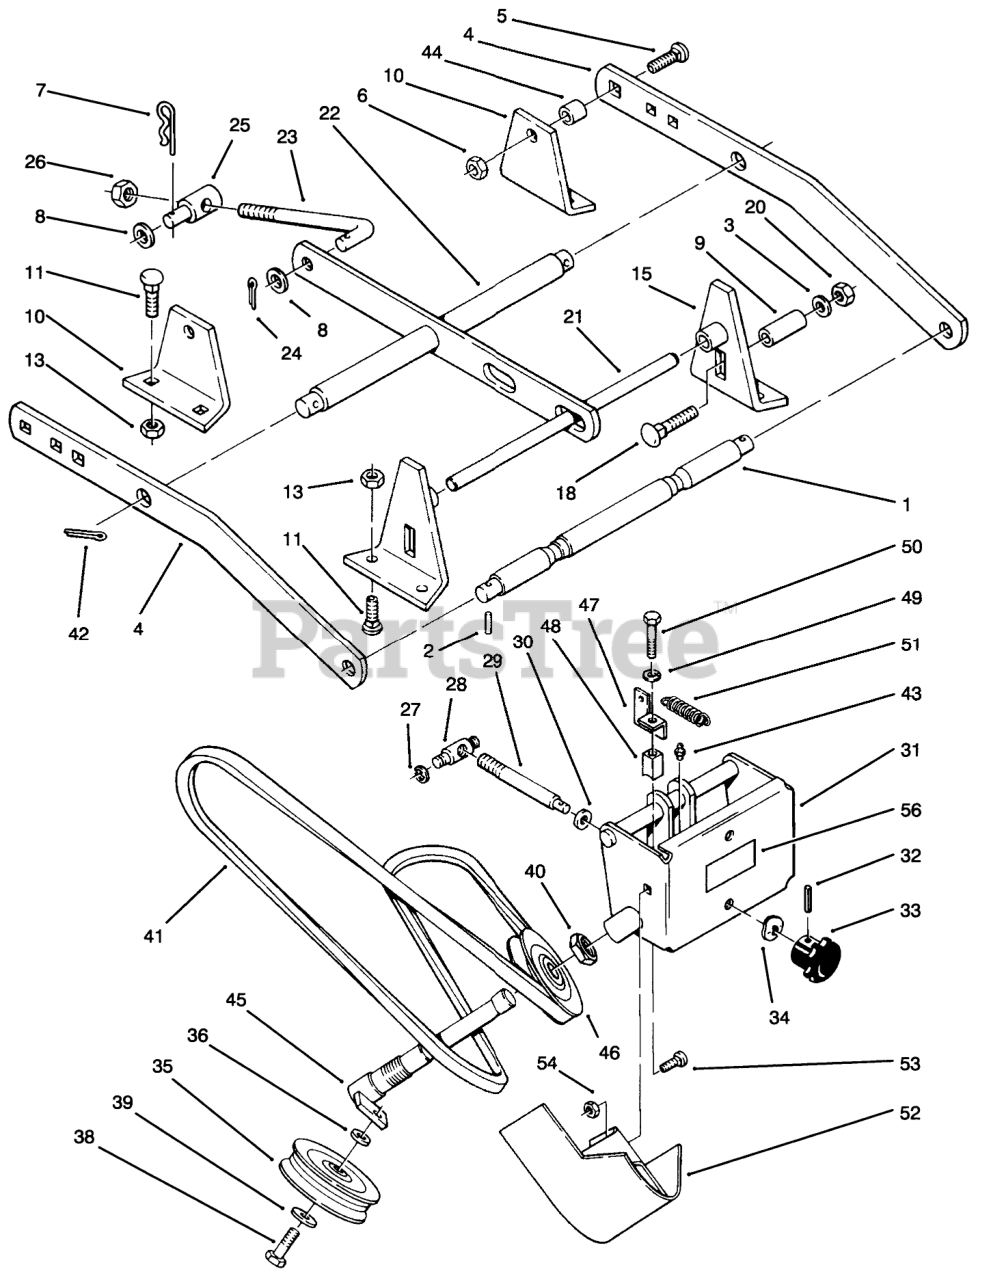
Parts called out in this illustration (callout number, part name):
1	Shaft
3	WASHER-FLAT
4	Bar-Draft
5	BOLT-CARR
6	LOCKNUT-FLANGE
7	PIN-HAIR
8	WASHER-FLAT
9	SPACER
10	Rear Deck Bracket
11	BOLT-CARR
13	NUT-LOCK, NI
15	Front Deck Bracket
18	BOLT-CARR
21	Front Shaft
22	Leveler
23	ROD LEVELER
24	PIN-COTTER
25	TRUNION
26	NUT-LOCK, NI
27	RING-RETAINING
28	TRUNNION-DOUBLE
29	ROD ADJ
30	WASHER-FLAT
31	Front Idler Support
32	PIN-ROLL
33	KNOB-ADJUSTMENT
34	WASHER-SPRING
35	PULLEY-FLAT IDLER
36	SPACER
38	SCREW-HH
39	WASHER-FLAT
40	NUT-JAM
41	BELT-103" A SECTION
42	PIN-COTTER
43	FITTING-GREASE
44	SPACER
45	ASS'Y-IDLER ARM
46	Pulley-V
47	Bracket
48	BLOCK-GUIDE
49	WASHER-LOCK
50	SCREW-HH
51	SPRING-BRAKE
52	Cover
53	BOLT-CARR
54	NUT-LOCK, NI
56	DECAL-ATTACH A-MATIC
